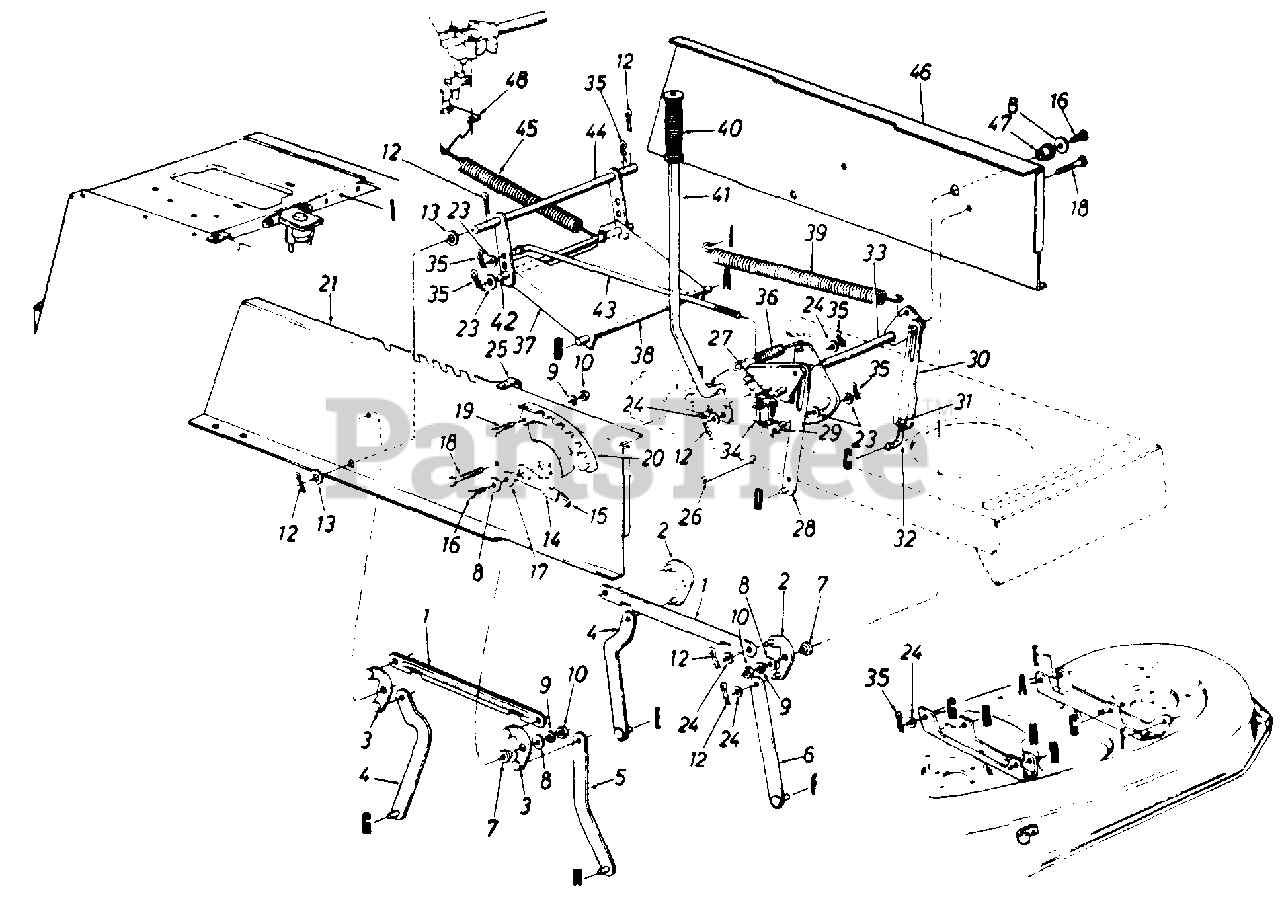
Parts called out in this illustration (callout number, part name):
1	Connecting Rod
2	Pivot Link Ass'y. - L.H.
3	Pivot Link Ass'y. - R.H.
7	Shld. Spacer .318" I.D.
8	Fl-Wash. .344" I.D. x .62" O.D.
9	L-Wash. 5/16" I.D.
10	Hex Nut 5/16-18 Thd.
12	Cotter Pin 1/8" Dia.
13	Fl-Wash. .635" I.D. x 1.0" O.D.
14	Deck Lift - Down Stop
16	Hex Wash. TT-Tap Scr. 5/16-18 x .75" Lg.
17	Flange Brg. .63" I.D.
18	Hex Wash. Hd. Scr. 5/16-18 x .875" Lg.
19	Hex Bolt 5/16-18 x .75" Lg.
20	Index Brkt.
21	Upper Frame - R.H.
23	Fl-Wash. .385" I.D. x .87" O.D.
24	Fl-Wash. .531" I.D. x .93" O.D.
26	Running Board Rod
27	Hex Wash. Hd. Tap Scr.
31	Hex Nut 1/2-20 Thd. (Gr. 5)
32	Lift Link Adjuster
35	Inter. Cotter Pin 3/8" Dia.
36	Extension Spring
37	Stabilizer Bracket
38	Shaft 1/2" Dia. x 10.28" Lg.
39	Extension Spring
40	Grip (Lift Handle)
41	Deck Lift Handle Ass'y.
42	Shaft 3/8" Dia. x 9.34" Lg.
43	Disengagement Rod
44	Stabilizer Shaft Ass'y.
45	Extension Spring 7.58" Lg.
46	Upper Frame - L.H.
47	Flange Brg. .632" I.D.
48	Spring Retainer Brkt.
